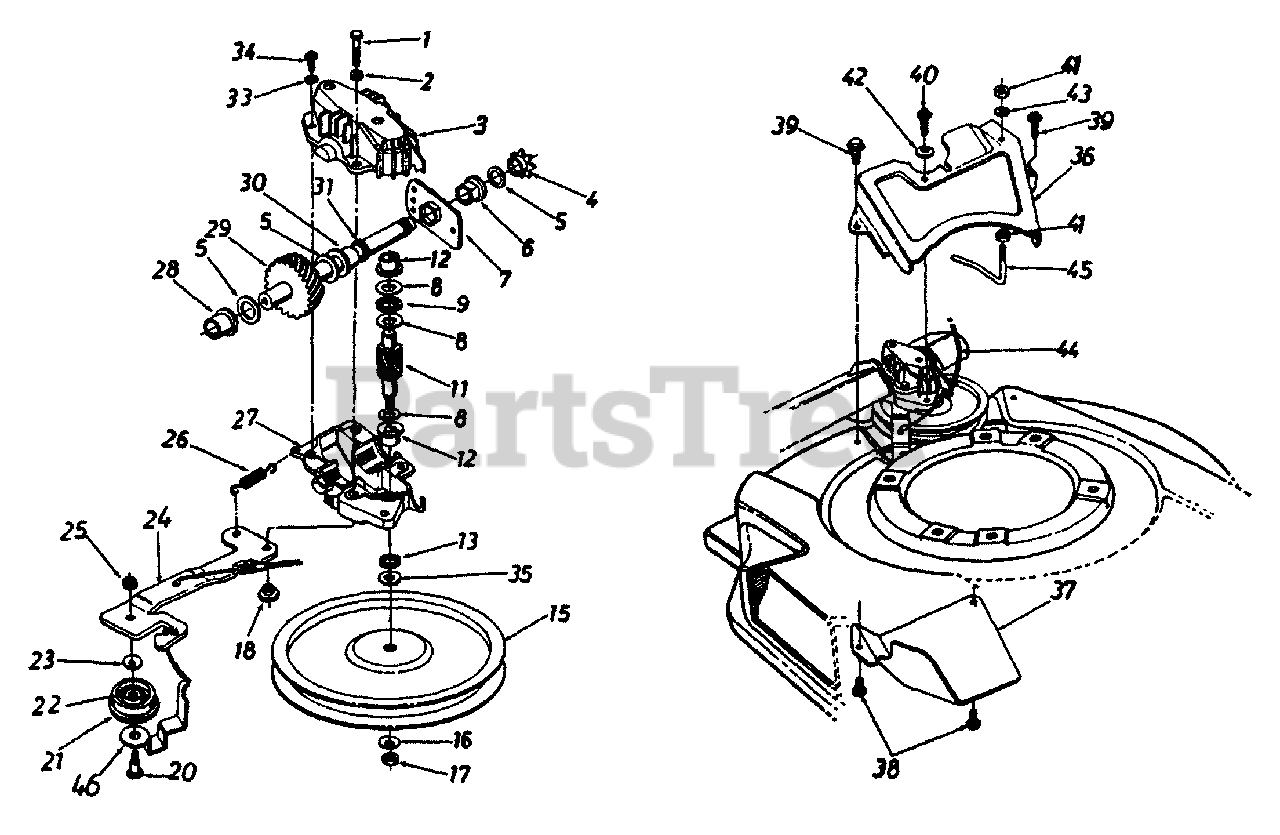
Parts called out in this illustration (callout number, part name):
1	Hex Bolt 1/4-20 x 1.25" Lg.
2	L-Wash. 1/4" I.D.
3	Upper Hsg. Half
4	#48 Sprocket 7 Tooth x 1/2 Pitch
5	Fl-Wash. 5/8" I.D. x .030
6	Hex Flange Brg. .631" I.D.
8	Thrust Wash. .382" I.D. x .70" O.D.
9	Thrust Bearing .375" I.D. x .812" O.D.
11	11 Tooth Helical Gear
12	Flange Bearing
13	Oil Seal
15	Fl-Pulley 5.06" I.D.
16	Bell-Wash. .265" I.D. x .75"
17	Hex Nut 1/4-28 L.H. Thd.
18	Shld. Spacer .375" Dia. x .170
20	Shld. Bolt .375" Dia. x .40"
21	Fl-Idler Plastic 1.50" Dia.
22	Needle Brg. .375" x .375"
23	Bell-Wash. .265" I.D. x .75"
24	Idler Brk't. Ass'y.
25	Hex Patch L-Nut 1/4-28 Thd.
26	Extension Spring 1.12" Lg.
27	Lower Hsg. Half
28	Flange Bearing .56 Dia.
29	Shaft Ass'y.
30	Flange Bearing .629 Dia.
31	Oil Seal .625 Dia.
33	L-Wash. #10 I.D.
34	Hex B-Tap Scr. #10 x .62"
35	Hex Washer .26" x .88"
39	Hex AB-Tap Scr. 1/4 x .50" Lg.
40	Hex B-Tap Scr. 1/4 x .62" Lg.
41	Hex Nut 1/4-20 Thd.
42	Bell-Wash. .265" I.D. x .75"
43	L-Wash. 1/4" I.D.
44	S.P. Cable - 48" Lg.
45	S.P. Belt Guard
46	Belt Guard
